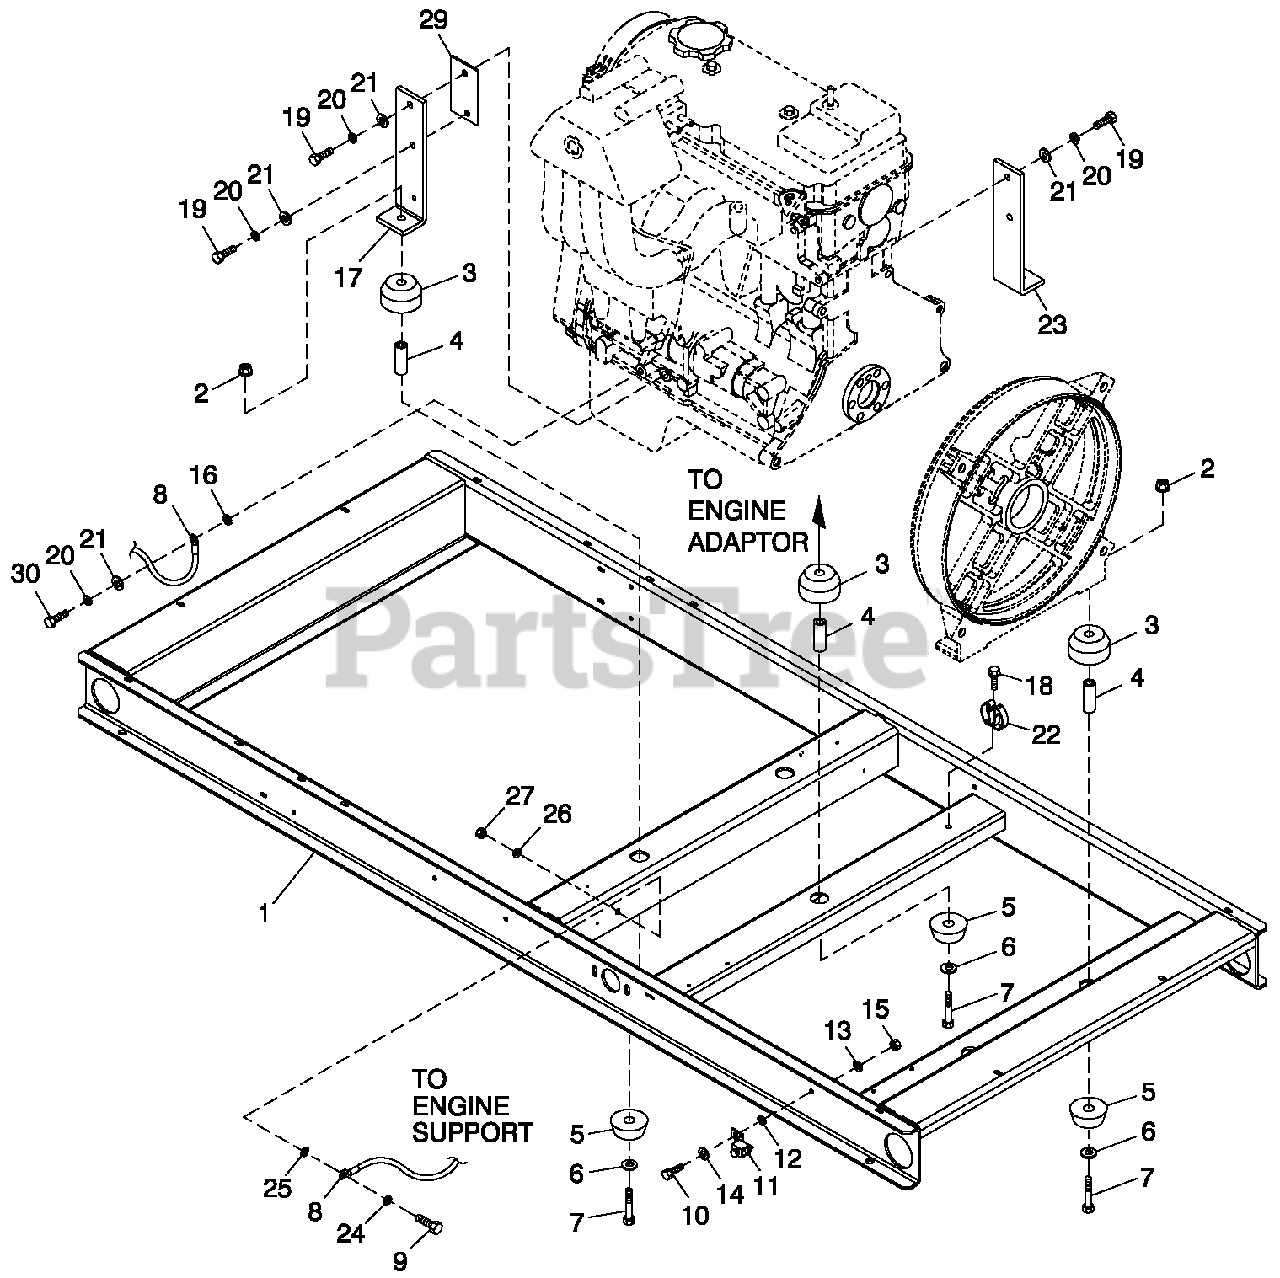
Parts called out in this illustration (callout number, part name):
1	WELDMENT FRAME 2.4L C2
2	NUT FLANGED HEX M12-1.75
3	DAMPENERVI B RATION 40 BLUE
4	SPACER .49 X .62 X 1.87 PWDR/ZNC
5	DAMPENERVI B RATION
6	WASHER FLAT M12
7	SCREW HHC M12-1.75 X 80 G8.8
8	ASSY WIRE 14.00"
9	SCREW HHC M8-1.25X 30 G8.8
10	SCREW HHC M6-1.0X 16 G8.8
11	LUG SLDLSS #2-#8X 17/64 CU
12	WASHER SHAKEPROOFINT 1/4
13	WASHER LOCK M6-1/4
14	WASHER FLAT M6-1/4 ZINC
15	NUT HEX M6 -1.0 G8YEL CHR
16	WASHER SHAKEPROOF INT 3/8
17	SUPPORT LH ENGINE 2.4L
18	SCREW HHTT M4-0.7X8BP
19	SCREW HHC M10-1.25 X 30 G8.8
20	WASHER LOCK 7/16
21	WASHER FLAT 3/8-M10 ZINC
22	SPRING CLIP HOLDER .37-.62
23	SUPPORT RH ENGINE 2.4L
24	WASHER LOCK M8-5/16
25	WASHER SHAKEPROOF INT 5/16
26	WASHER FLAT 5/16-M8 ZINC
27	NUT HEX M8-1.25 G8 CLEAR ZINC
29	SPACER ENGINE MOUNT (2.4L G1)
30	SCREW HHC M10-1.25 X 25 C8.8
